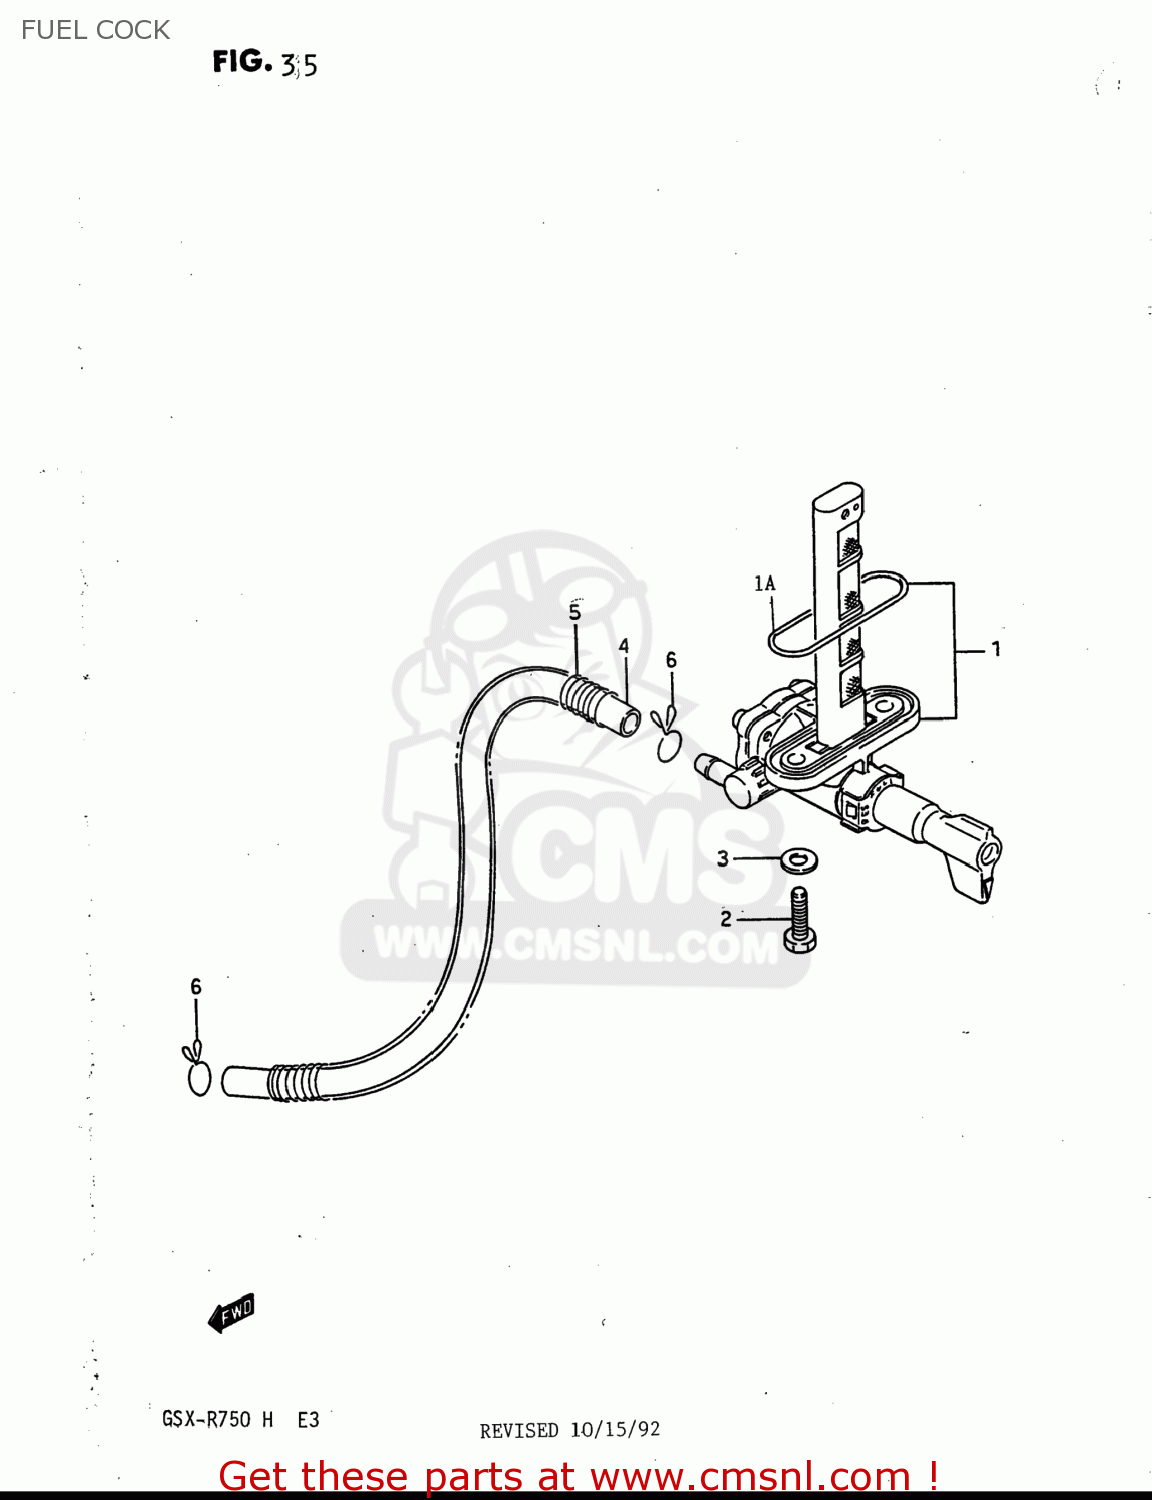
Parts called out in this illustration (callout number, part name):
1	COCK ASSY,FUEL
2	BOLT(6X20)
3	GASKET
4	HOSE
5	SPRING
6	CLIP
